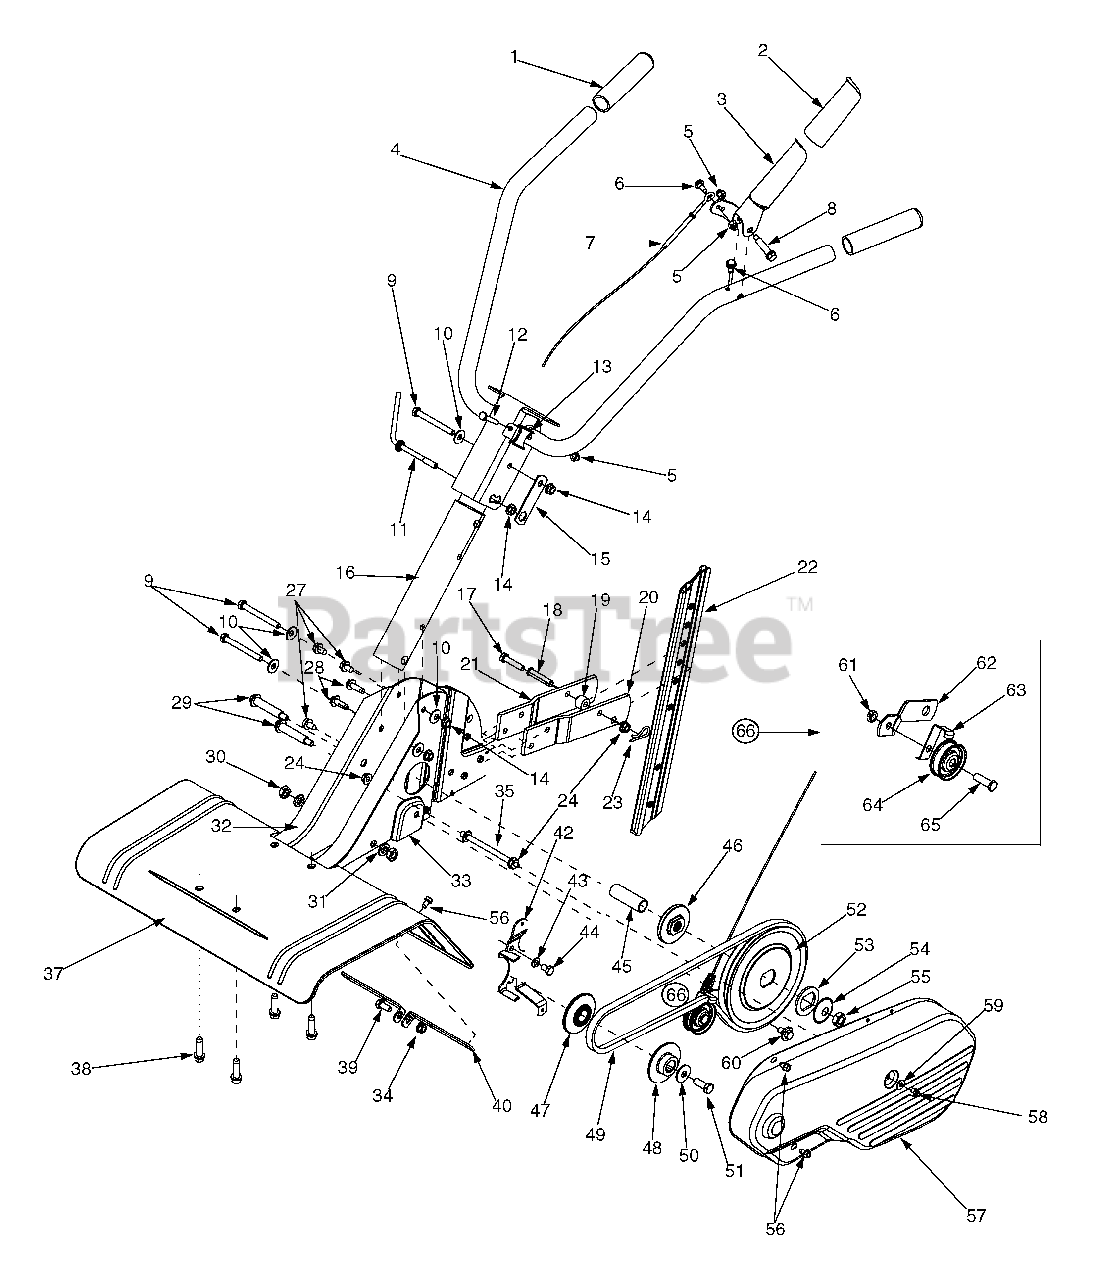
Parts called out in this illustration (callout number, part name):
2	Clutch Grip
5	Lock Nut Cap 1/4-20
6	Shoulder Screw
7	Clutch Cable
8	Shoulder Screw
9	Hex Cap Screw 5/16-18 x 3.0
10	Bell Washer.340 ID x.872 OD
11	Adjustable Handle Crank
12	Hex Cap Screw 1/4-20 x 1.5
13	Rope Guide
14	Flange Nut 5/16-18
15	Retainer Bracket
18	Clevis Pin 3/8 x 1.62
19	Spacer
23	Cotter Pin
24	Hex Flange Locknut 5/16-18
27	Hex Washer Screw 5/16-18 x.625
28	Hex Washer Screw 5/16-18 x 1.0
29	Shoulder Screw
30	Jam Nut 7/16-20
31	Lock Washer 7/16
35	Belt Cover Bolt
39	Hex Cap Screw 5/16-18
43	Lock Washer 5/16
44	Hex Cap Screw 5/16-24 x.50
45	Input Spacer.64 ID x 2.4 Lg
46	Pulley Adapter
47	Engine Inner Half Pulley
48	Engine Outer Half Pulley
49	Belt
50	Bell Washer.396 ID x 1.140 OD
51	Hex Cap Screw 3/8-24 x 1.0
52	Flat Pulley
53	Retainer Bearing Washer
54	Spherical Washer.531 ID x.620 OD
55	Jam Nut 1/2-20
56	Hex Washer Screw 1/4-20 x.50
58	Cap Lock Nut 1/4-28
59	Flat Washer.271 ID x.630 OD
60	Shoulder Screw
61	Jam Nut 3/8-16
63	Idler Belt Keeper
64	Flat Idler
65	Hex Cap Screw 3/8-16 x 1.25
66	Idler Bracket Assembly
